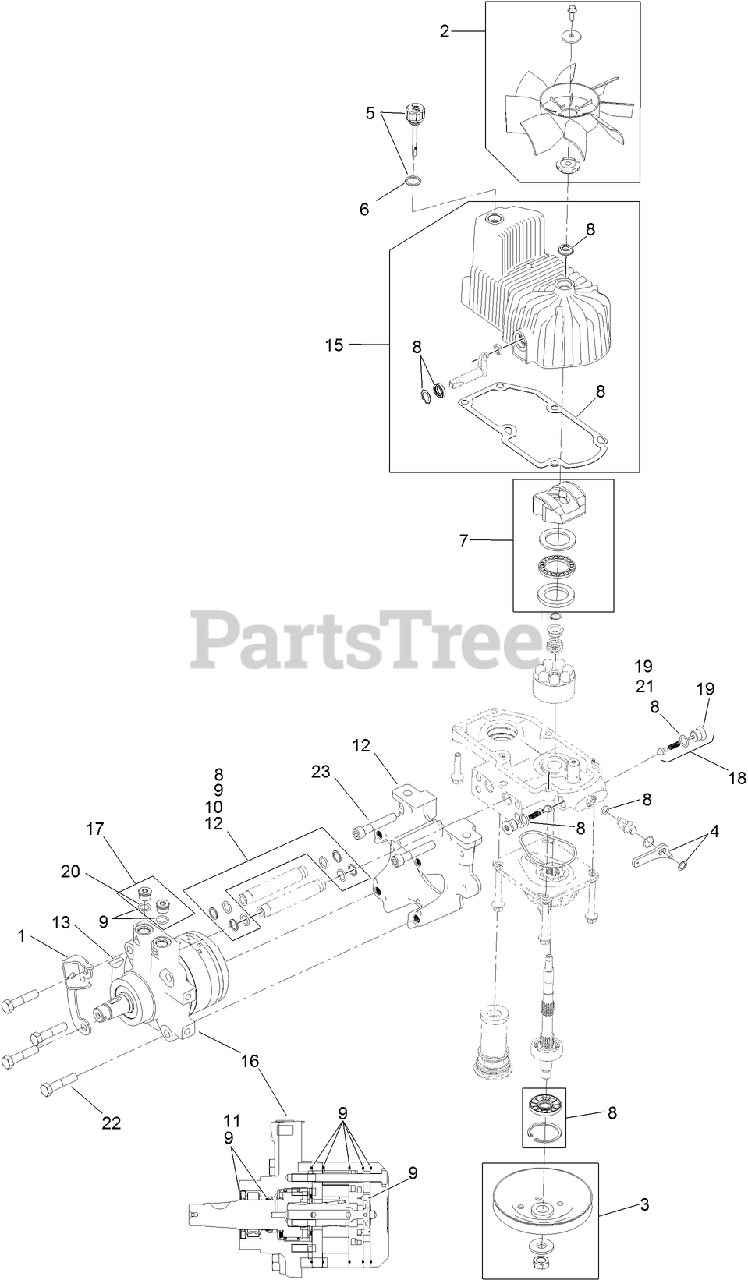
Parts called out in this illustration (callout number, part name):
1	BRACKET-ANCHOR, CABLE
2	FAN KIT
3	PULLEY KIT
4	HANDLE-BYPASS VALVE, HYDRO
5	DIPSTICK-HYDRO W/GASKET
6	GASKET-DIPSTICK, HYDRO
7	SWASH BLOCK KIT
8	PUMP SEAL KIT
9	MOTOR SEAL KIT
10	TUBE SEAL KIT
11	OUTPUT SHAFT SEAL KIT
12	NOSE CUP-UHT
13	KEY-WOODRUFF
15	Housing-LH
16	MOTOR-HYDRAULIC LH 240CC
17	MAGNETIC PLUGS SERVICE KIT
18	CHECK VALVE ASM
19	PLUG-CHECK (W/O-RING)
20	O-RING
21	O-RING-CHECK VALVE
22	SCREW HH
23	SCREW-HSH
